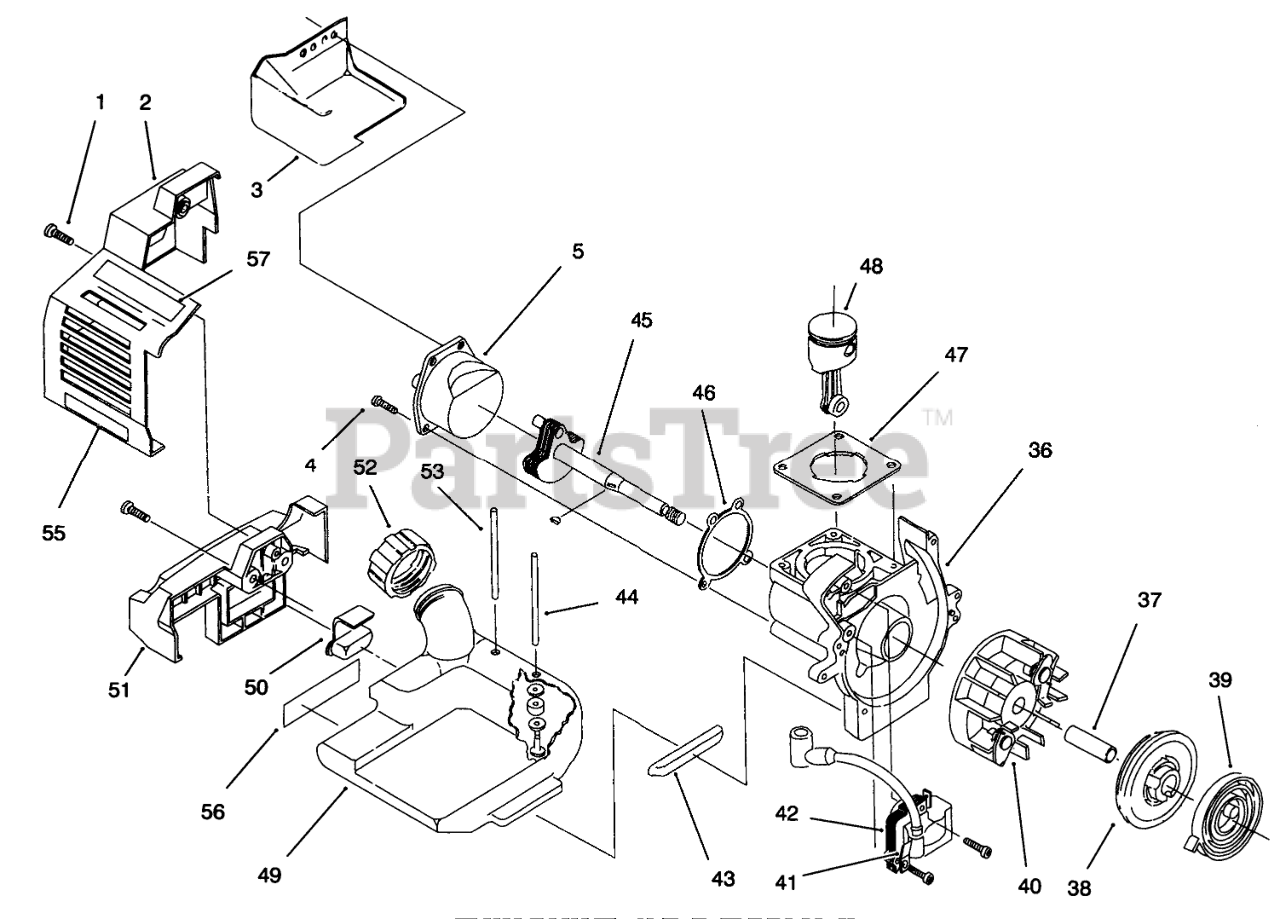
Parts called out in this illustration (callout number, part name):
3	HEAT SHIELD
5	CRANKCASE CAP
39	RECOIL SPRING
40	FLYWHEEL
42	MODULE ASM
45	POWER SHAFT ASM
46	CRANKCASE CAP GASKET
47	CYLINDER GASKET
48	PISTON & ROD ASM
50	REAR FUEL TANK PAD
57	DECAL - CARBURETOR
